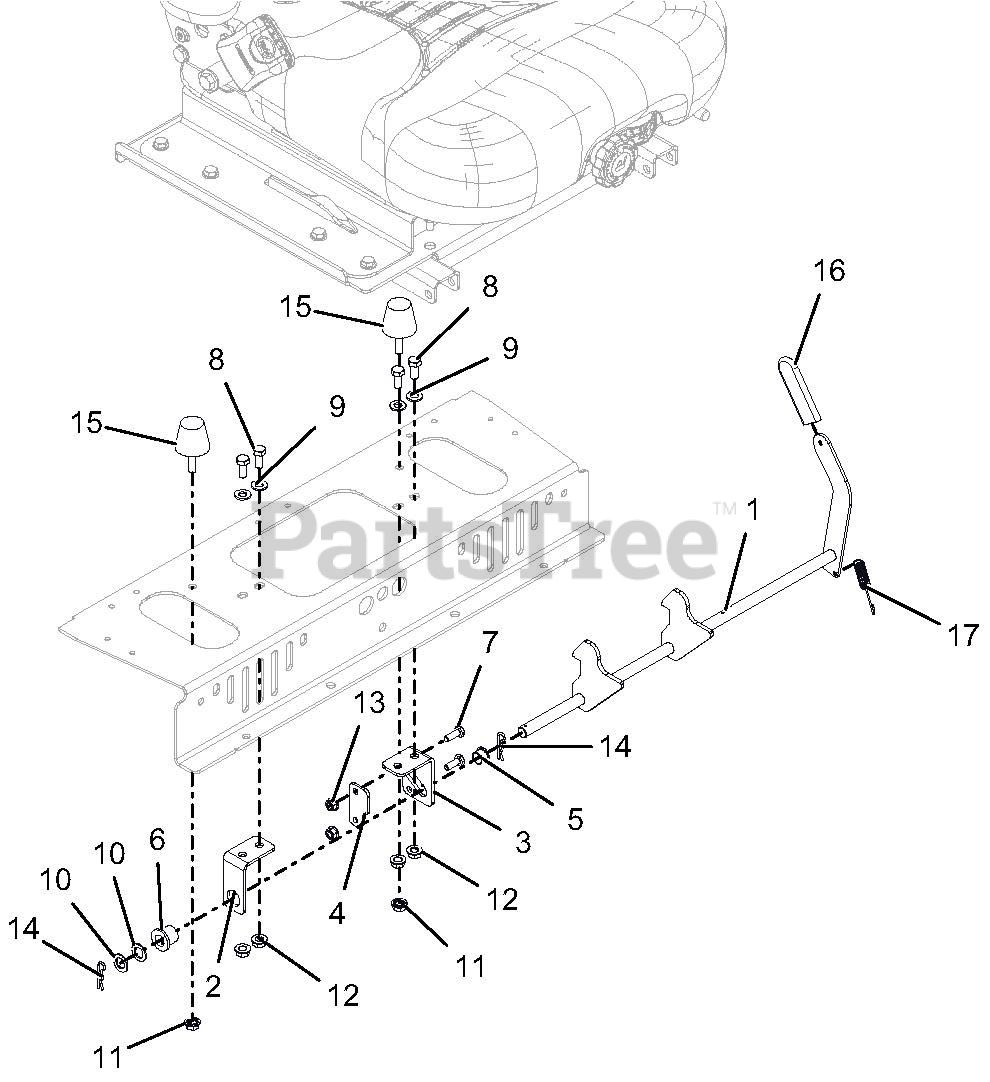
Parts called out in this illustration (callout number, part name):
1	WMT, SEAT LATCH
2	MOUNT, SEAT LATCH - RH
3	MOUNT, SEAT LATCH - LH
4	RETAINER-SEAT LATCH
5	BUSHING, POLYLINER - .50 SPLIT
6	BSHG, FLANGE .515 X .750 X .745 X 1.00 NYLON
7	BLT-HEX .25-20X.75 GR5 YWZC
8	BLT-HEX .31-18X.75 GR5 YWZC
9	WSHR-FL-STL.344X.688X.065YWZC
10	WSHR-FL-STL .520X.827X.062 YWZC
11	@NUT-SPNLK-FLG .312-18 YWZC
12	NUT, LK-TOP-FLG .312-18 YWZC
13	NUT, LK-TOP-FLG .25-20 YWZC
14	PIN-HAIR INT .08X.38X1.42 YWZC
15	BUMPER, STUD MOUNTED CONE SHAPED
16	GRIP-VINYL-YELLOW .125 x 1.0 x 3.0
17	SPRG, EXTENSION
